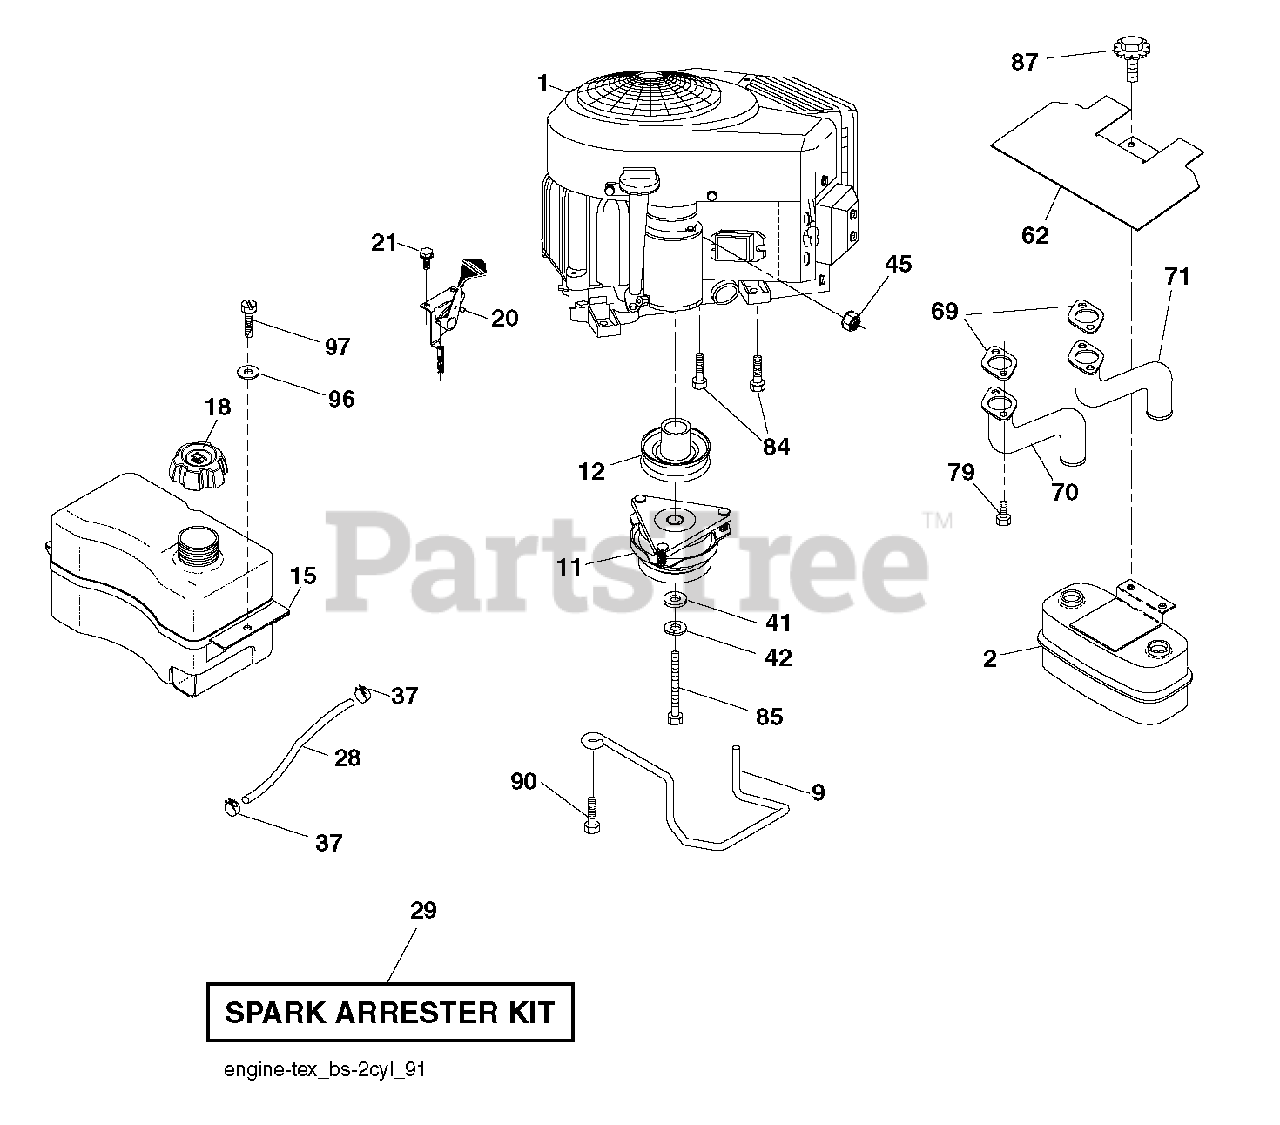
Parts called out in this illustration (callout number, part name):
2	MUFFLER.ASM.TWN.EXTNDED.DFLCTR
9	KEEPER BELT ENGINE
11	CLUTCH.ELECTRIC.LT.48"*
12	PULLEY.ENGINE.TUFFTORQ
15	TANK.ASSEMBL.2.5GAL.NON-EPA
18	CAP ASM.FUEL.2.25"FR.
20	CONTROL.TH/CK.COBRA.B&S.TWN.
21	SCREW.#10 X 0.750.BOS
28	LINE.FUEL.20
29	KIT.SPARK ARRESTOR 794945 B&S
37	HOSE CLAMP
42	LOCKWASHER
45	NUT
62	SHIELD.HEAT.MUFFLER
69	GASKET.MUFFLER
70	RP.EXHAUST.TUBE.LH.BS/TWIN
71	EXHAUST.TUBE.RH.BS/TWIN
79	SCREW.SOCKET.HEAD.5/16-18
84	SCREW.3/8-16
85	BOLT HEX 7/16-20X4-1/4"
87	BOLT, 5/16-18 X 1 3/4
90	SCREW 3/8-16X1
